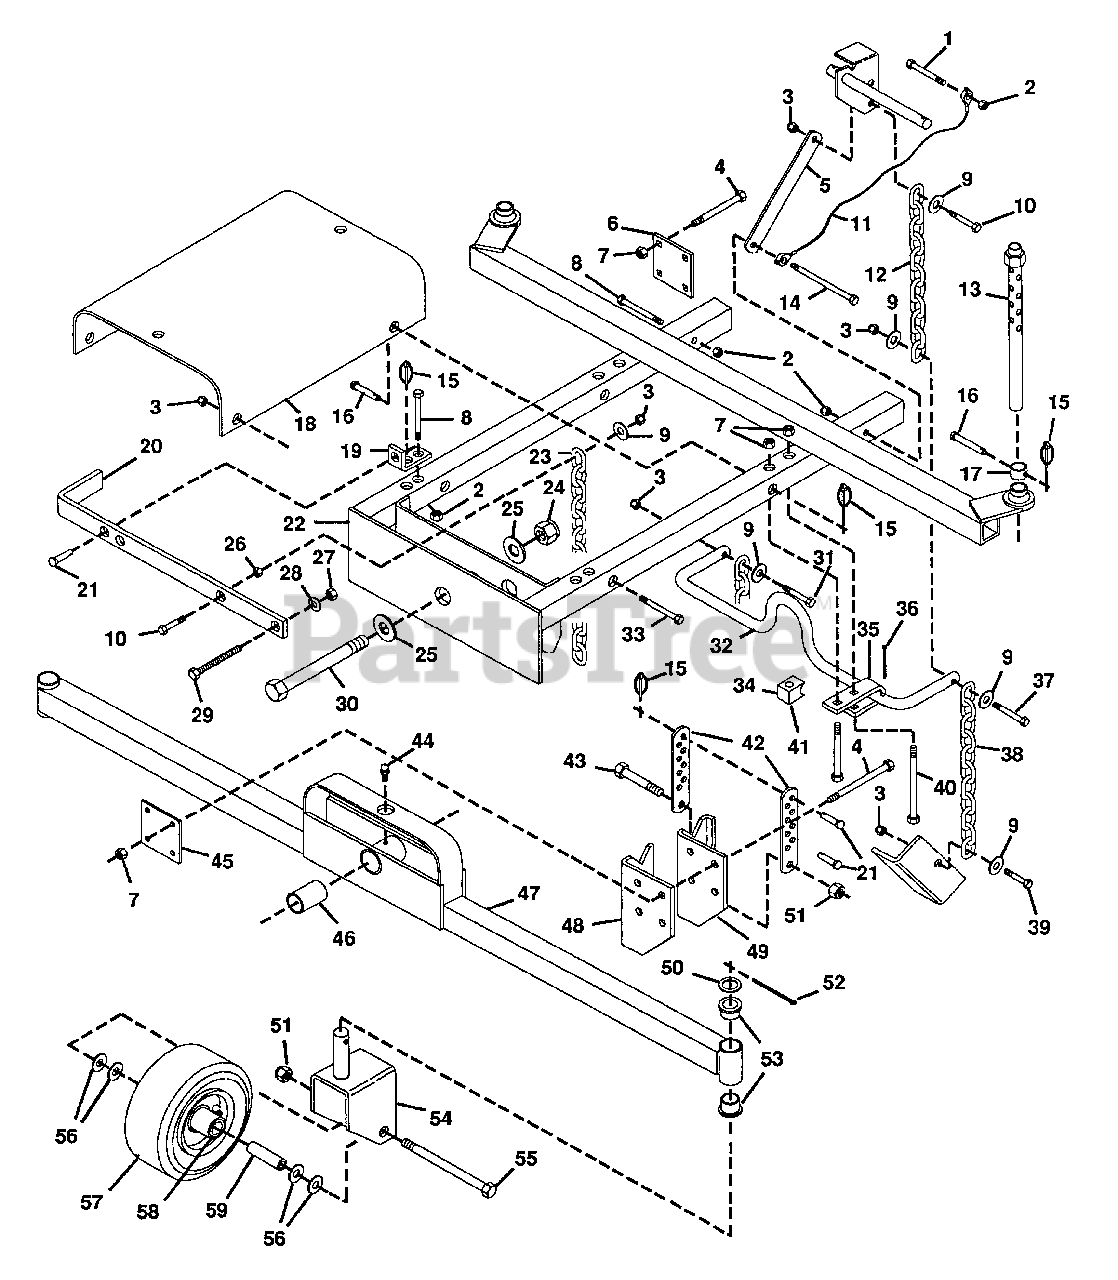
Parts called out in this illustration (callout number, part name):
1	BOLT, HEX 5/16-24X2.25
2	NUT, LOCK 5/16-24
3	NUT, LOCK 5/16-18
4	BOLT, HEX 3/8-16X3.25
5	BAR, DECK LIFT
6	PLATE, ATTACHMENT CLAMP
7	NUT, LOCK 3/8-16
8	BOLT, HEX 5/16-24X2.75
9	WASHER, FLAT .406X.812X.065
10	BOLT, HEX 5/16-18X1.25
11	CABLE, STOP
12	CHAIN, LIFT
13	WELDMENT, HEIGHT ADJUSTMENT ROD
14	BOLT, HEX 5/16-24X3.5
15	KLIK PIN
16	PIN, CLEVIS 3/8X2.62
17	SPACER, HEIGHT ADJUSTMENT
18	GUARD, PTO SHAFT
19	BRACKET, LIFT PIVOT
20	BAR, LIFT
21	PIN, CLEVIS
22	WELDMENT, MOWER FRAME
23	CHAIN, HEIGHT ADJUSTMENT
24	NUT, LOCK 3/4-10
25	WASHER, FLAT .812X1.469X.130
26	NUT, JAM 5/16-18
27	NUT, JAM 3/8-16
28	WASHER, LOCK 3/8
29	BOLT, HEX 3/8-16X3.00 SPECIAL
30	BOLT, HEX 3/4-10X4.50
31	BOLT, HEX 5/16-18X1.50
32	ARM, PIVOT
33	BOLT, HEX 5/16-18X2.50
34	STOP, NYLON
35	BRACKET, AXLE SUPPORT
36	PIN, COTTER 1/8X1.25
37	BOLT, HEX 5/16-18X1.75
38	CHAIN, LIFT
39	BOLT, HEX 5/16-18X1.00
40	BOLT, HEX 3/8-16X4.00
41	BOLT, HEX 3/8-16X3.00
42	STRAP, ADJUSTMENT
43	BOLT, HEX 1/2-13X2.00
44	FITTING, LUBE 1/4-28
45	PLATE, ADJUSTMENT CLAMP
46	TUBE, PIVOT
47	WELDMENT, AXLE
48	PLATE, HEIGHT ADJUSTMENT-L.H.
48	PLATE, HEIGHT ADJUSTMENT-R.H.
49	PLATE, HEIGHT ADJUSTMENT-L.H.
49	PLATE, HEIGHT ADJUSTMENT-R.H.
50	RACE, BEARING THRUST
51	NUT, LOCK 1/2-13
52	PIN, COTTER .187X1.62
53	BUSHING, PIVOT
54	WELDMENT, CASTER FORK
55	BOLT, HEX 1/2-13X5.00
56	WASHER, FLAT .531X1.250X.100
57	WHEEL, GAUGE
58	BEARING, GAUGE WHEEL
59	BUSHING, WHEEL .520X.750X3.312
NS	DECAL, PRO MASTER-60
